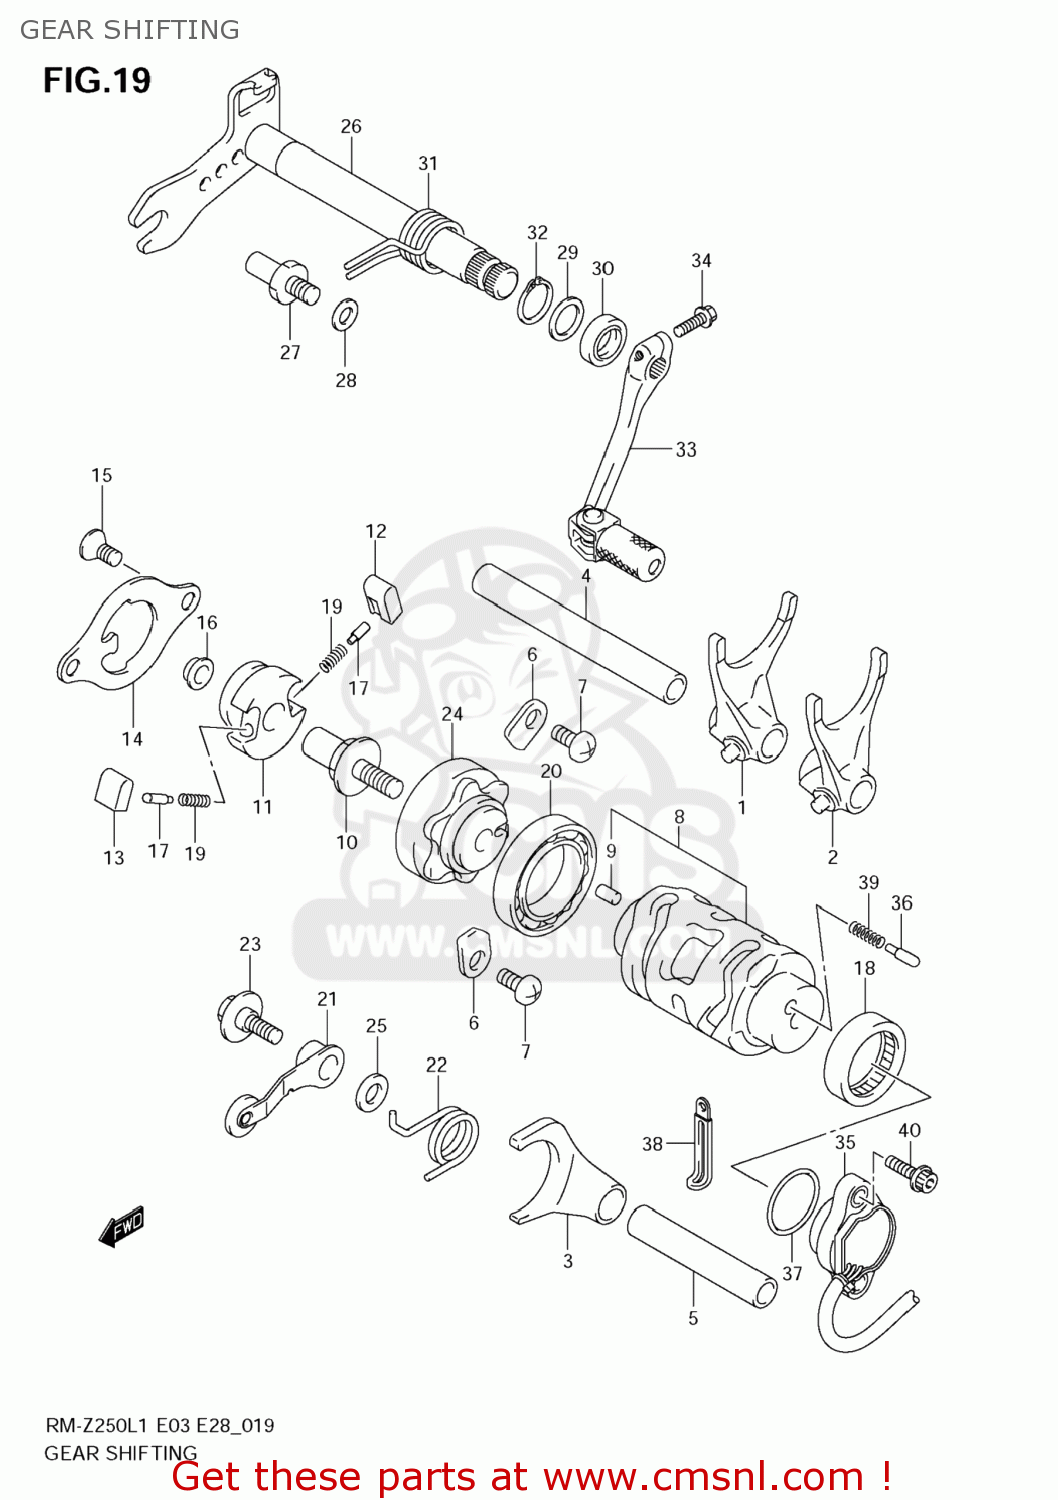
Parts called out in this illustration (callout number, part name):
1	FORK,GEAR SHIFT NO.1
2	FORK,GEAR SHIFT NO.2
3	FORK,GEAR SHIFT NO.3
4	SHAFT,GEAR SHIFT FORK(L:95)
5	SHAFT,GEAR SHIFT FORK(L:60)
6	RETAINER
7	BOLT(6X12)
8	CAM,GEAR SHIFT
9	PIN
10	PIN,GEAR SHIFT CAM
11	SHIFTER,GEAR SHIFT CAM
12	PAWL,GEAR SHIFT NO.1
13	PAWL,GEAR SHIFT NO.2
14	LIFTER,GEAR SHIFT PAWL
15	SCREW(6X12)
16	SPACER(7X10X5)
17	PIN
18	BEARING(25X32X12)
19	SPRING
20	BEARING
21	STOPPER,GEAR SHIFT CAM
22	SPRING,GEAR SHIFT CAM STOPPER
23	BOLT,SHIFT CAM STOPPER
24	PLATE,GEAR SHIFT CAM STOPPER
25	WASHER
26	SHAFT,GEAR SHIFT
27	STOPPER,GEAR SHIFT ARM
28	SHIM(8.8X14X1)
29	SHIM(14X20X1)
30	SEAL,OIL(14X22X7.3)
31	SPRING
32	CIRCLIP
33	LEVER ASSY,GEA
34	BOLT
35	BASE ASSY,GEAR SHIFT TERMINAL
36	PIN(5X15.5)
37	O RING(D:2.4,ID:26.2)
38	CLAMP(L:45)
39	SPRING
40	BOLT
